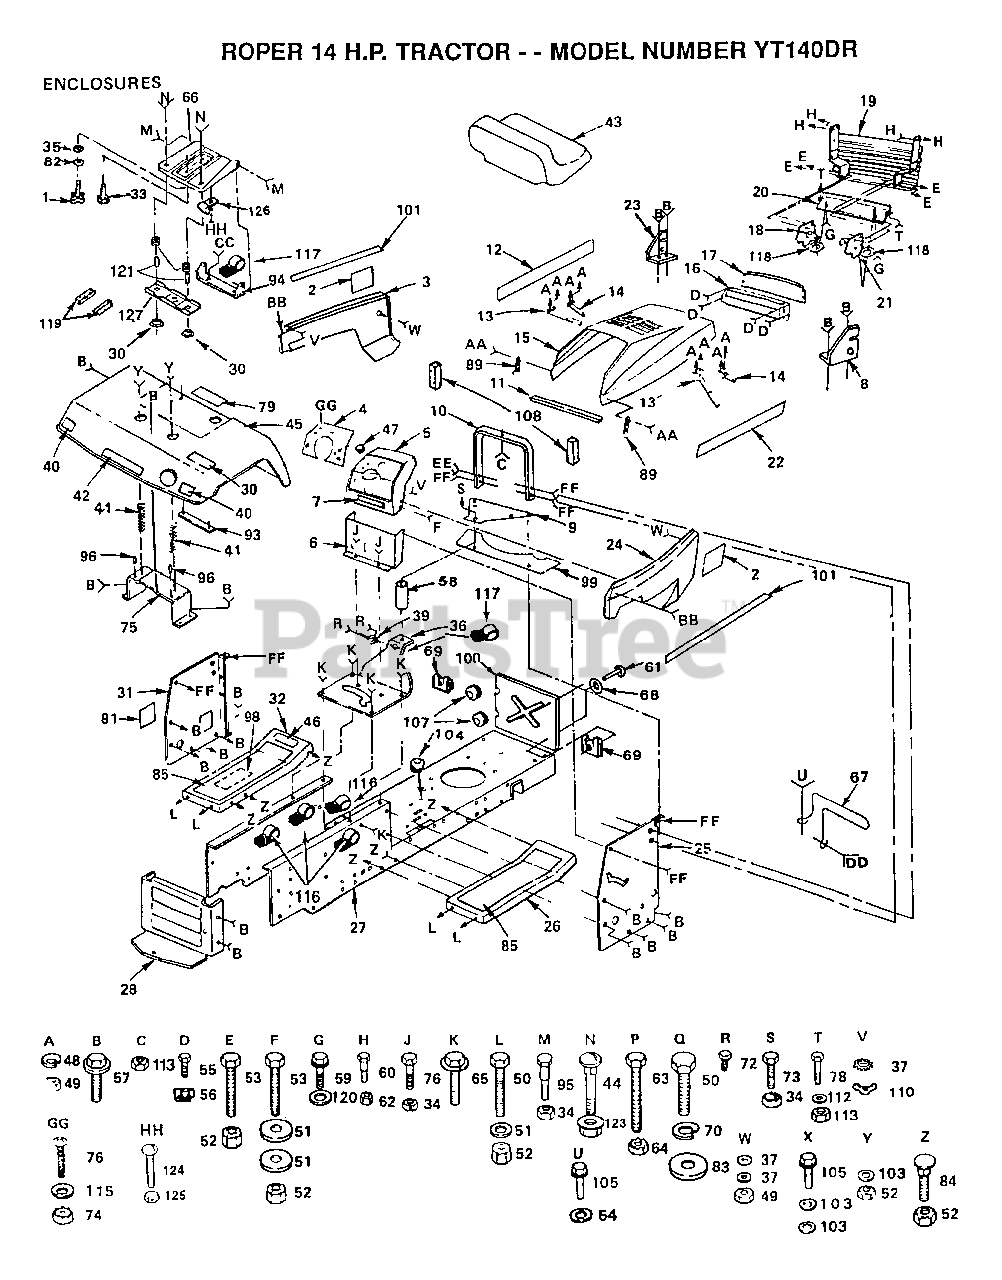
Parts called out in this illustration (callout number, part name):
1	"KNOB 1/2"" YT"
6	LOWER DASH
8	SUPPORT RH YTH
11	FOAM STRIP T
17	LENS LT
18	SUPPORT LH YTH
21	SUPPORT RH YTH
23	SUPPORT LH YTH
27	CHASSIS ASSY
30	BUSHING
31	DASH PANEL T
32	FOOTREST LH YT
37	LOCKWASHER GT
40	REFLECTOR-TAIL YT
44	BOLT
46	DECAL T
47	PLUG BUTTON T
51	WASHER
53	BOLT
54	WASHER HYT
56	"""J"" FASTENER LT"
57	SCREW
58	SPACER
59	SCREW
60	BOLT T
64	NUT
65	SCREW LT
67	GUARD MUFFLER HYT
68	RETAINER LT
69	RECEPTACLE LT
70	LOCKWASHER
73	BOLT
76	SCREW
78	SCREW
79	DECAL
81	COVER ACCESS
83	WASHER T
84	BOLT
89	HOOD LATCH T
96	NUT-PUSH YT
99	REAR BAFFLE T
103	WASHER
104	SNAP BUSHING T
105	SCREW GTV
108	STRIP - FOAM
112	WASHER PM
115	WASHER
116	INSUL CLIP T
117	CLIP T
118	WASHER
119	STRIP FORM
120	WASHER M
121	SPACER SPLIT
123	NUT T
125	"NUT,KEPS"
127	BRKT SWITCH
